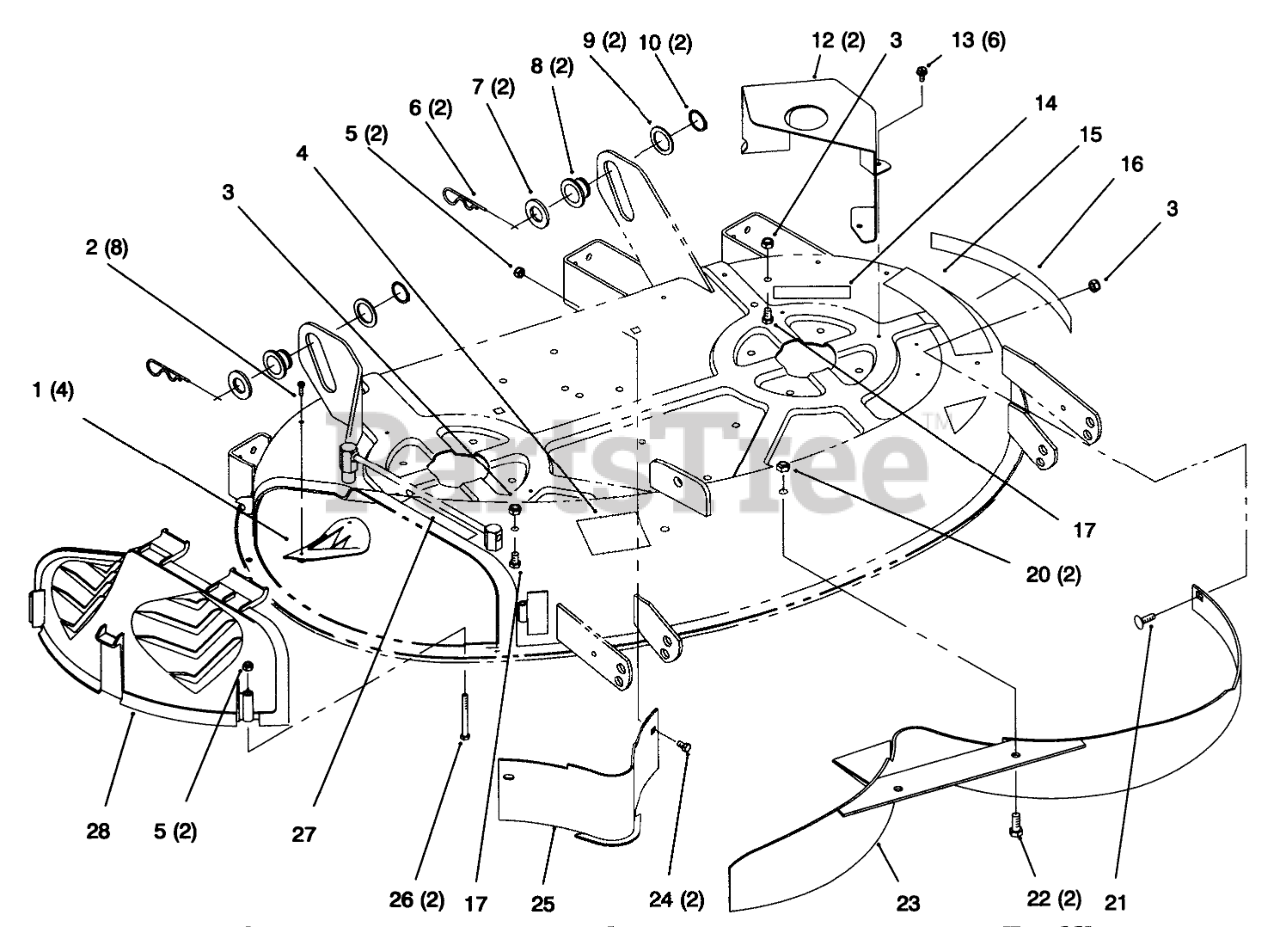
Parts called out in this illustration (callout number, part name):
1	PLATE-KICKER
2	SCREW-PPH
3	NUT-LOCK, NI
4	Decal-Routing
5	NUT-LOCK, NI
6	PIN-HAIR
7	WASHER-FLAT
8	ROLLER-LIFT
9	WASHER
10	RING-RETAINING
12	COVER-BELT
13	SCREW-HWHTF
15	Decal-Dange
15	DECAL - DANGER
16	DECAL-RECYCLER DECK 38"
17	SCREW-HH
20	NUT-LOCK, NI
21	SCREW-HH
21	BOLT-CARR
22	SCREW-HH
23	BAFFLE ASM
24	SCREW-HH
25	BAFFLE ASM
26	SCREW-HH
27	DECAL-CAUTION
28	COVER-RECYCLER
